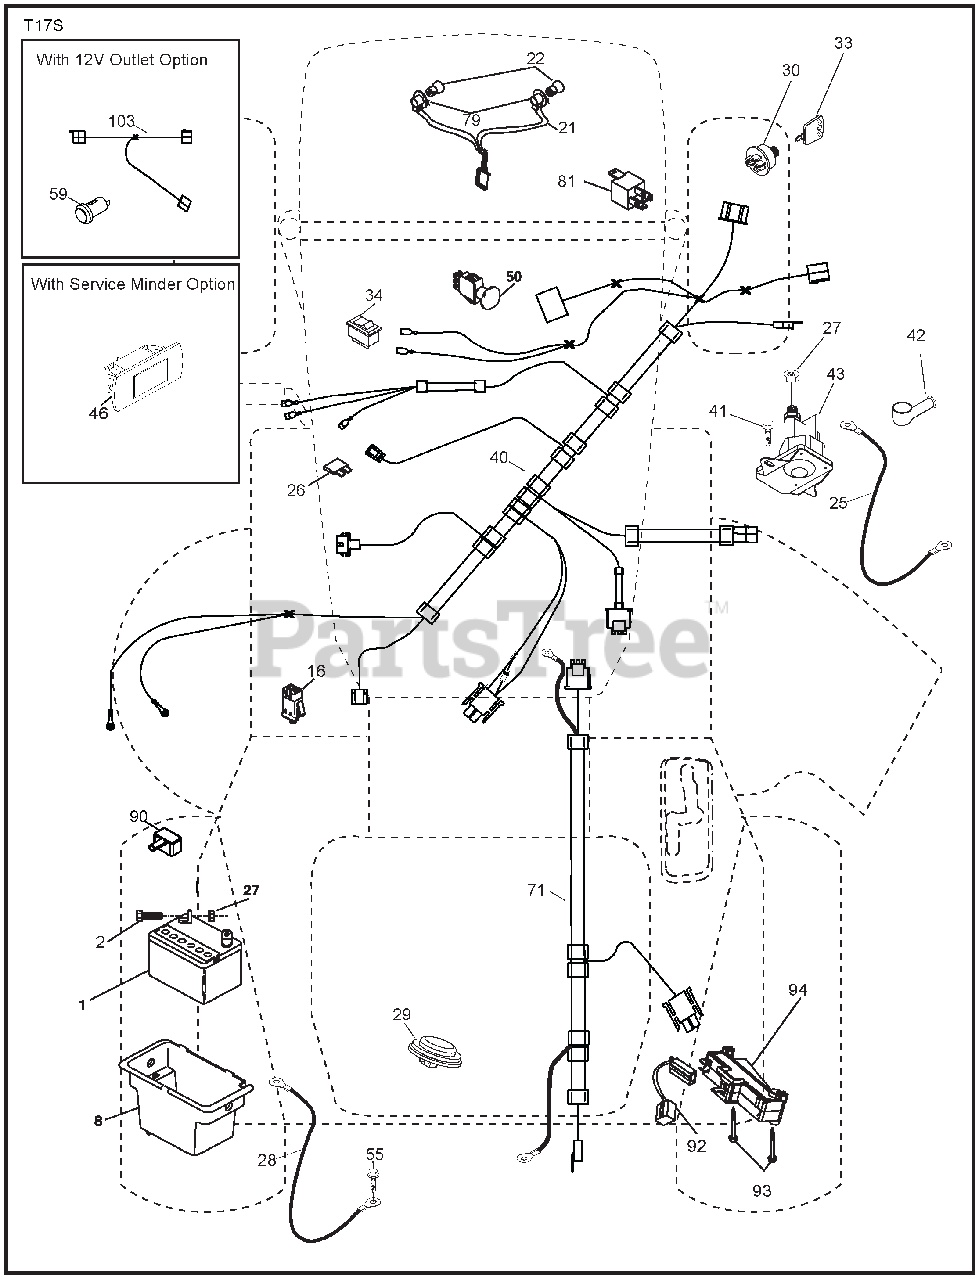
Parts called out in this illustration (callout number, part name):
1	BATTERY.12.VOLT.28.AMP.WET
2	BOLT.HEX.HD.1/4-20UNC X 3/4
8	BOX.BATTERY.MNT.REAR.LT.TEX.BL
16	SWITCH.INTERLOCK.NONO.GRAY
21	HARNESS ASM.LIGHT.22"(4152J)
22	BULB.LIGHT.#1156
25	CABLE.STARTER
26	FUSE.20 AMP.
27	Nut, Keps Hex 1/4-20 unc
28	CABLE.BLACK.22"REAR BATT.TEX
29	SWITCH.SEAT.DELTA.OPC.9LB.
30	SWITCH.IGN.DLTA.P-IN.ROS
33	KEY/CHAIN.BLISTER PACK.GEN.USA
34	SWITCH.LIGHT/RESET.B/B/RED.
40	HARNESS IGN ELEC RELAY
41	Screw 1/4-20 x 1/2
42	COVER.TERMINAL.RED
43	SOLENOID.W/BRASS PLUNGER.2005
46	HOUR METER
50	SWITCH.PTO.8 TERMINAL.BLACK
55	SCREW.5/16-18X3/4.SMGML.TAP/R
71	HARNESS.IGN.CHASS.TEX.REAR.BAT
79	SOCKET ASM.BULB.TWISTLOCK
81	RELAY HARNESS SEALED
90	COVER TERMINAL BATTERY FR. TEX
92	HARNESS.PIGTAIL.CONSLE.ROS.MLK
93	SCREW.PLASTITE.10-14 X 2.0
94	MODUAL REVERSE ROS
